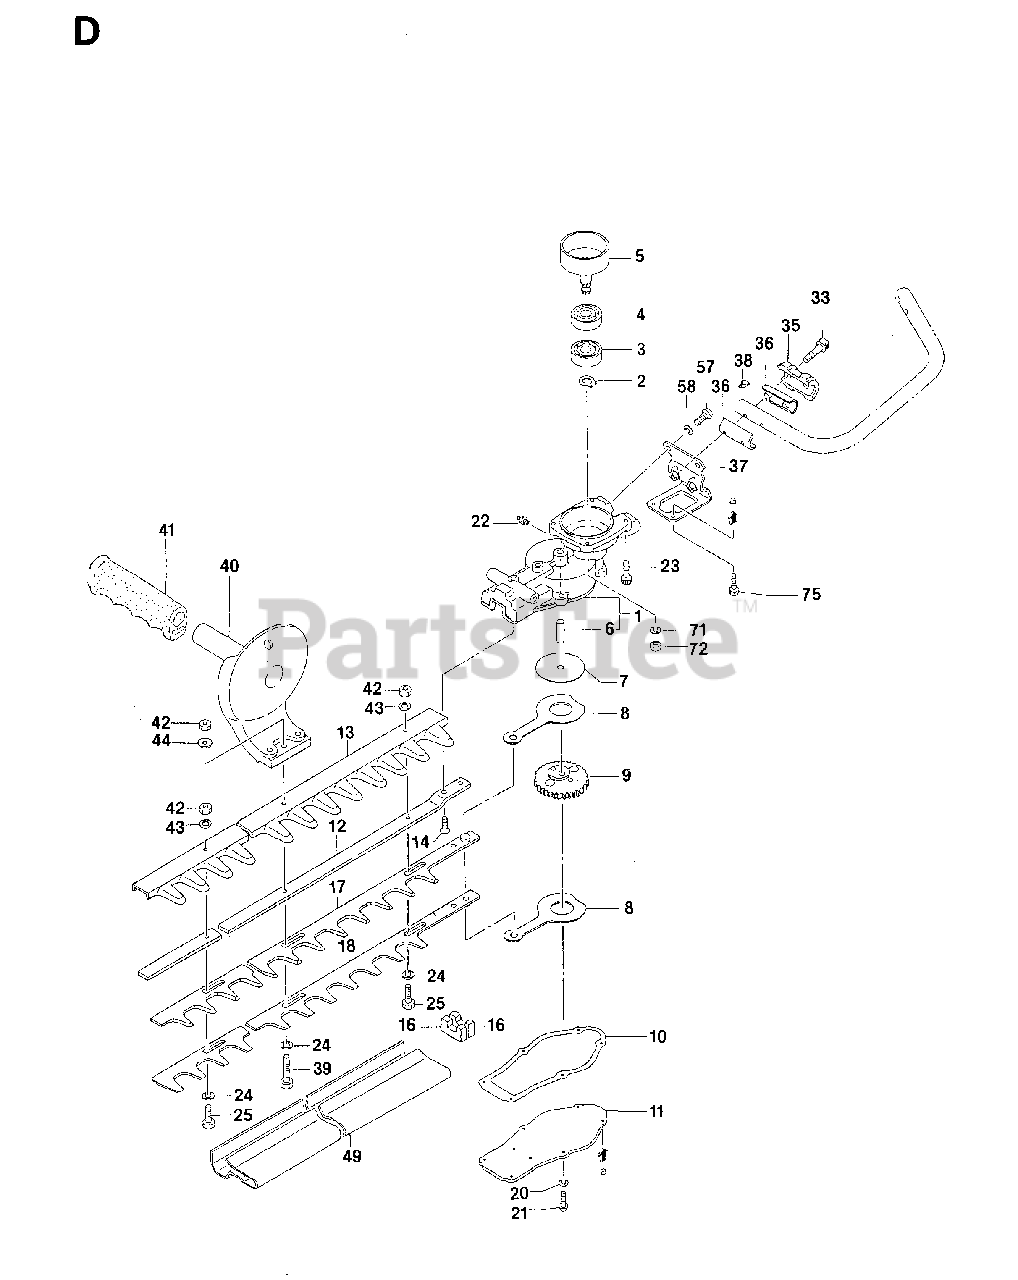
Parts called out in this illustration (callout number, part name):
2	RETAINING RING SGA 15
20	SPRING WASHER 4.1X7.1
25	BOLT
33	SCREW MC6S 5X35
42	NUT
43	SPRING WASHER
57	SCREW MC6S 5X12
58	SPRING WASHER
71	SPRING WASHER
72	NUT M6M M6
